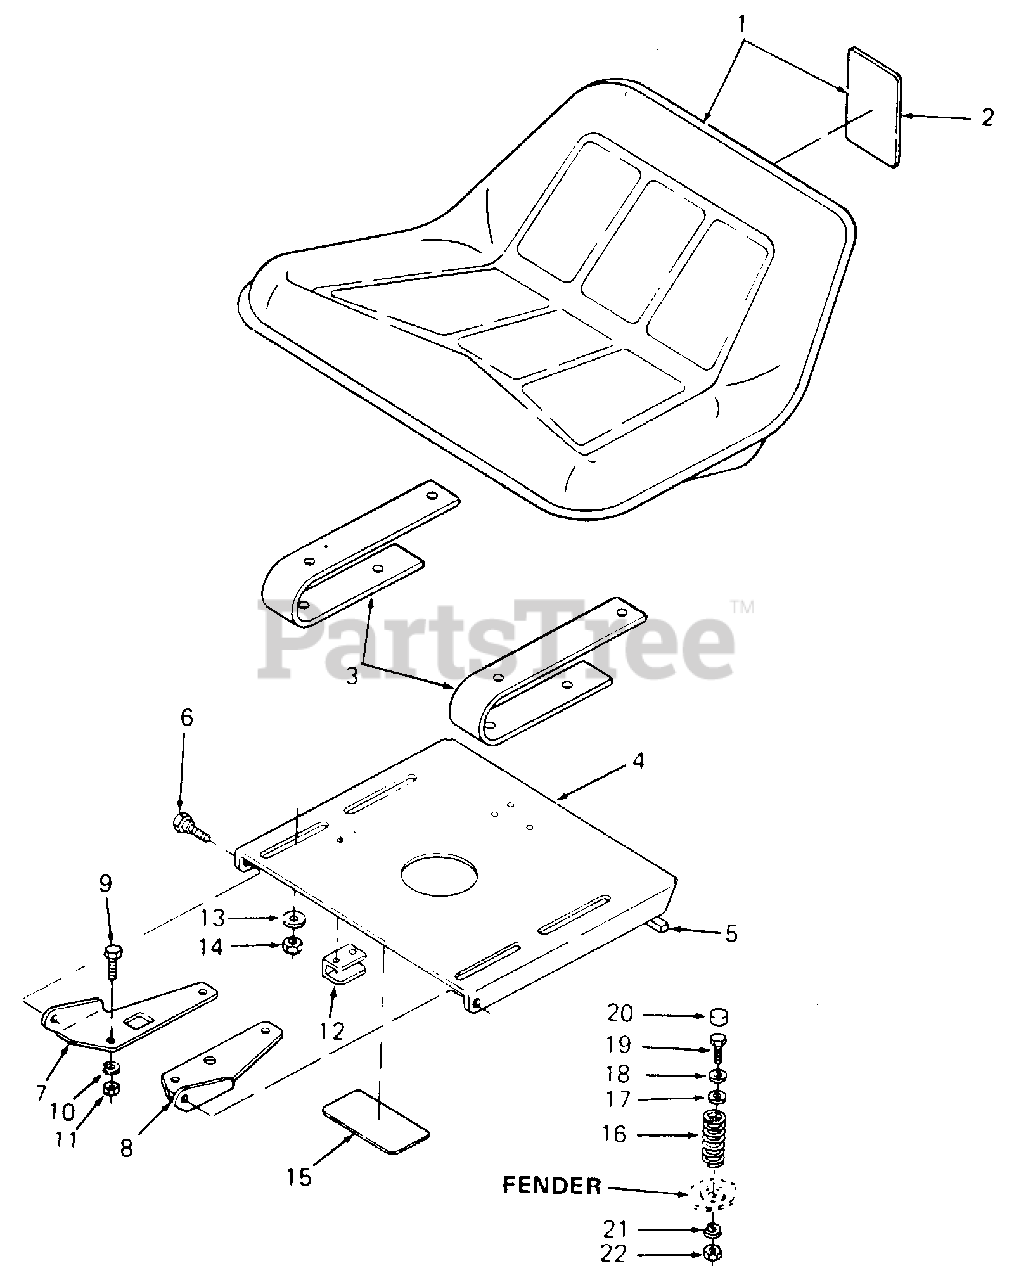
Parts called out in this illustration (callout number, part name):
1	Seat w/Graphic
2	Graphic, Caution
3	Spring, Seat
4	Cover, Battery Box
5	Bumper, Hood Adhesive, Locktite #495
6	Screw, Shoulder, .437 Dia X .162
7	Bracket, Pivot RH
8	Bracket, Pivot LH
9	Screw, Hex Cap, 5/16-18 X .75 Lg GR5
10	Washer, Lock, 5/16
11	Nut, Hex, 5/16-18 GR5
12	Channel, Switch Actuator
13	Washer, Belleville, .345 X .88 X .06
14	Nut, Hex, 5/16-18 GR5
15	Label, Booster Battery
16	Spring, Compression
17	Washer, Rubber
18	Washer, Flat, .344 X .875 X .06 Thk
19	Screw, Hex, Cap, 5/16-18 X 1.25 Lg GR5
20	Cap, Spring
21	Washer, Lock, 5/16
22	Nut, Hex, 5/16-18 GR5
